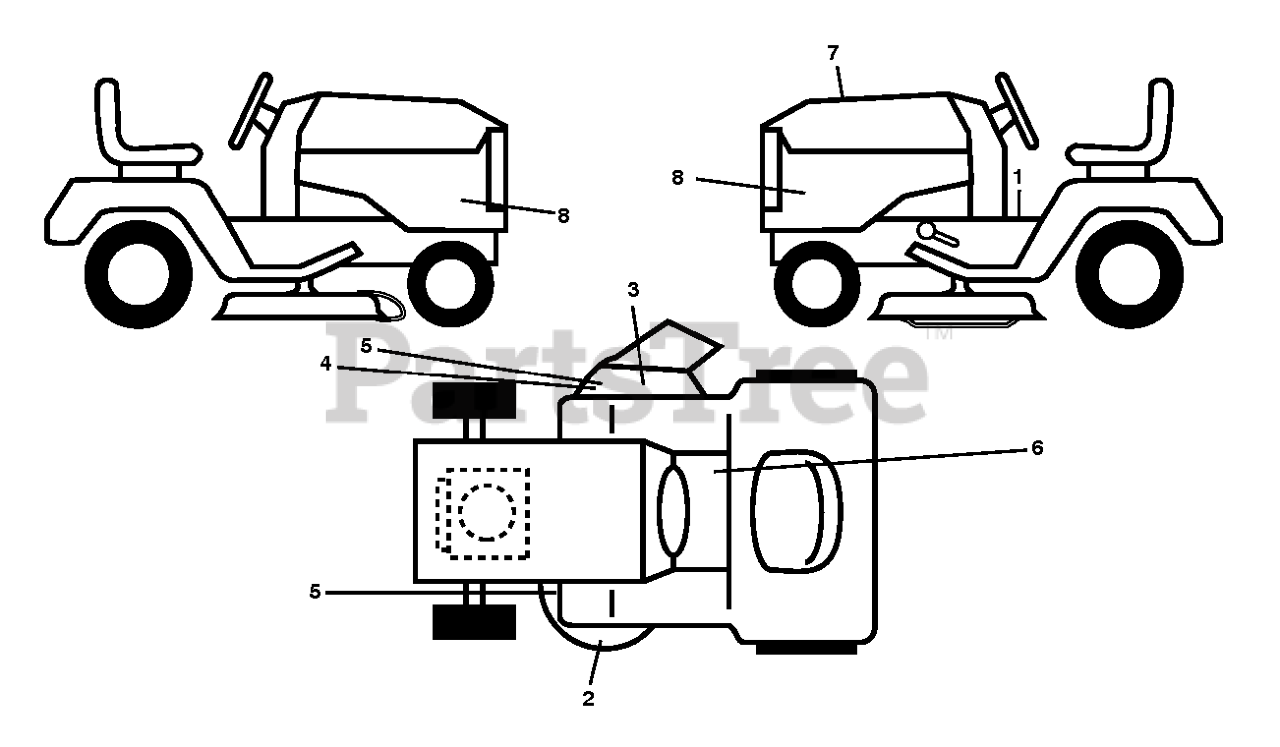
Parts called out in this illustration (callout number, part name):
1	DECAL.TRACTOR.SADDLE
2	DECAL.54DECK.CLEARCUT.VER2.18
3	DECAL.TRACT/ZTR.DECKWARN.HUSQ
4	DECAL BELT ROUTING DECAL DECAL
5	DECAL.DECK.CLEARCUT.NOSTEP
